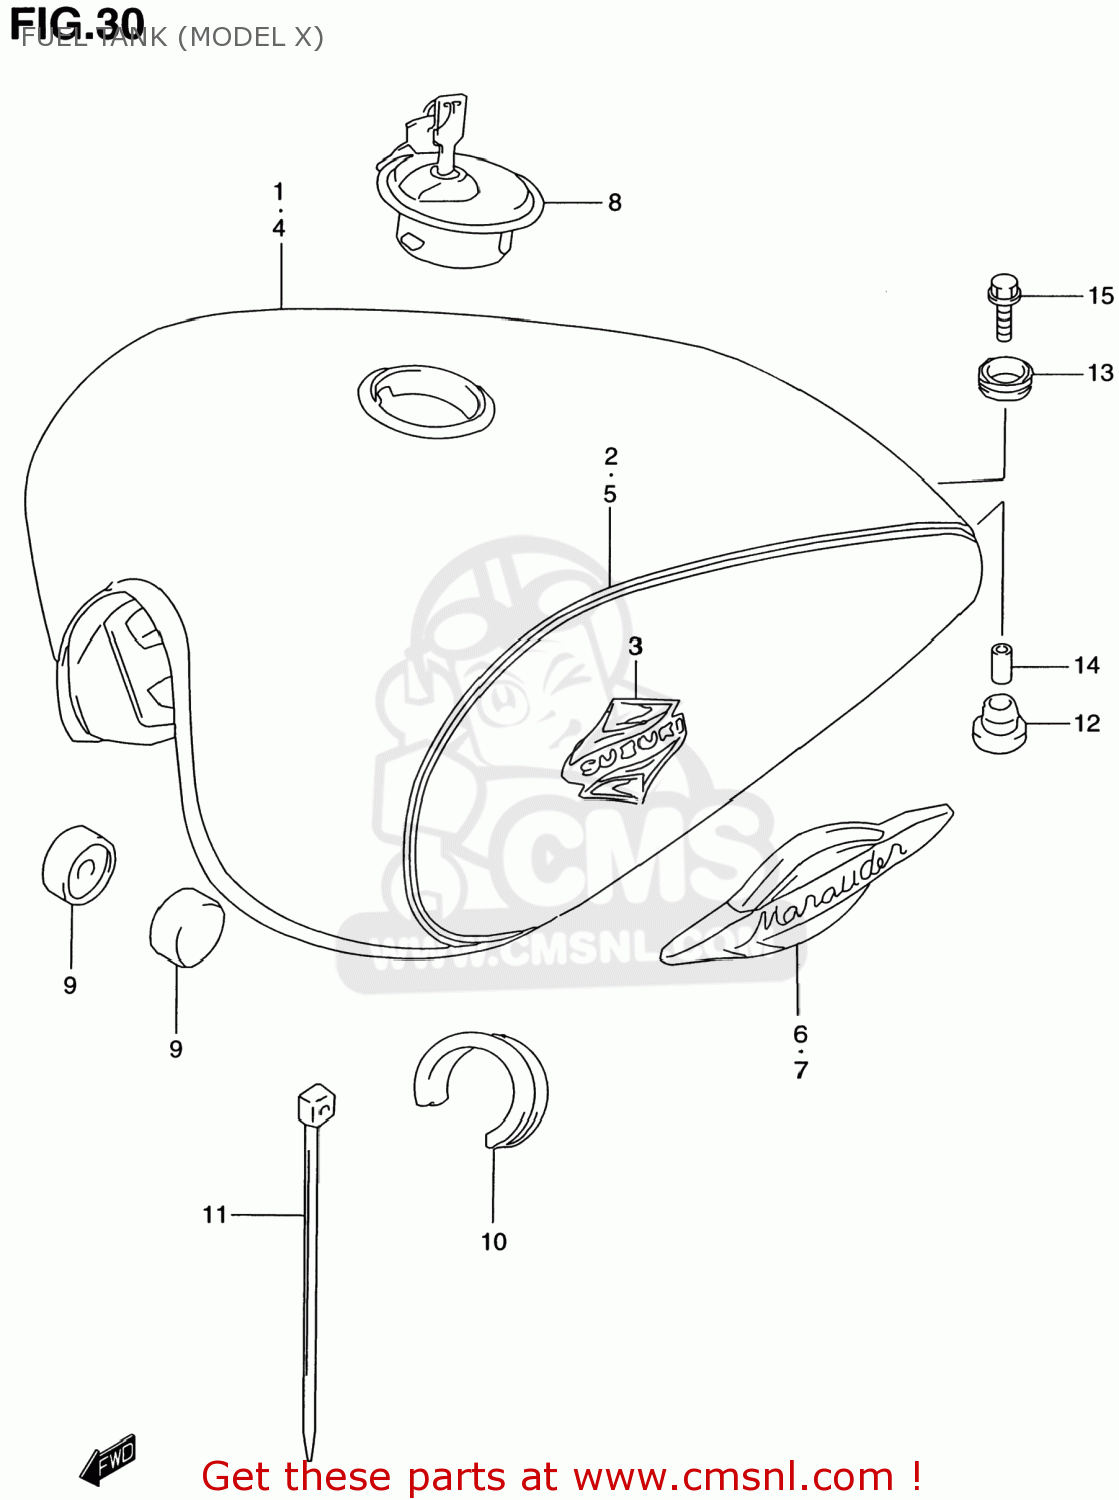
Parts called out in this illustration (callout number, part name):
1	TANK ASSEMBLY,FUEL
2	TAPE SET,FUEL TANK
3	EMBLEM,FUEL TANK
4	TANK ASSEMBLY,FUEL
5	TAPE SET,FUEL TANK
6	EMBLEM,FUEL TANK,RIGHT
7	EMBLEM,FUEL TANK,LEFT
8	CAP SET,FUEL TANK
9	CUSHION
10	CUSHION,FUEL TANK SIDE
11	CLAMP(L:250)
12	CUSHION
13	CUSHION,FUEL TANK RR
14	SPACER(6.5X9X18)
15	BOLT
